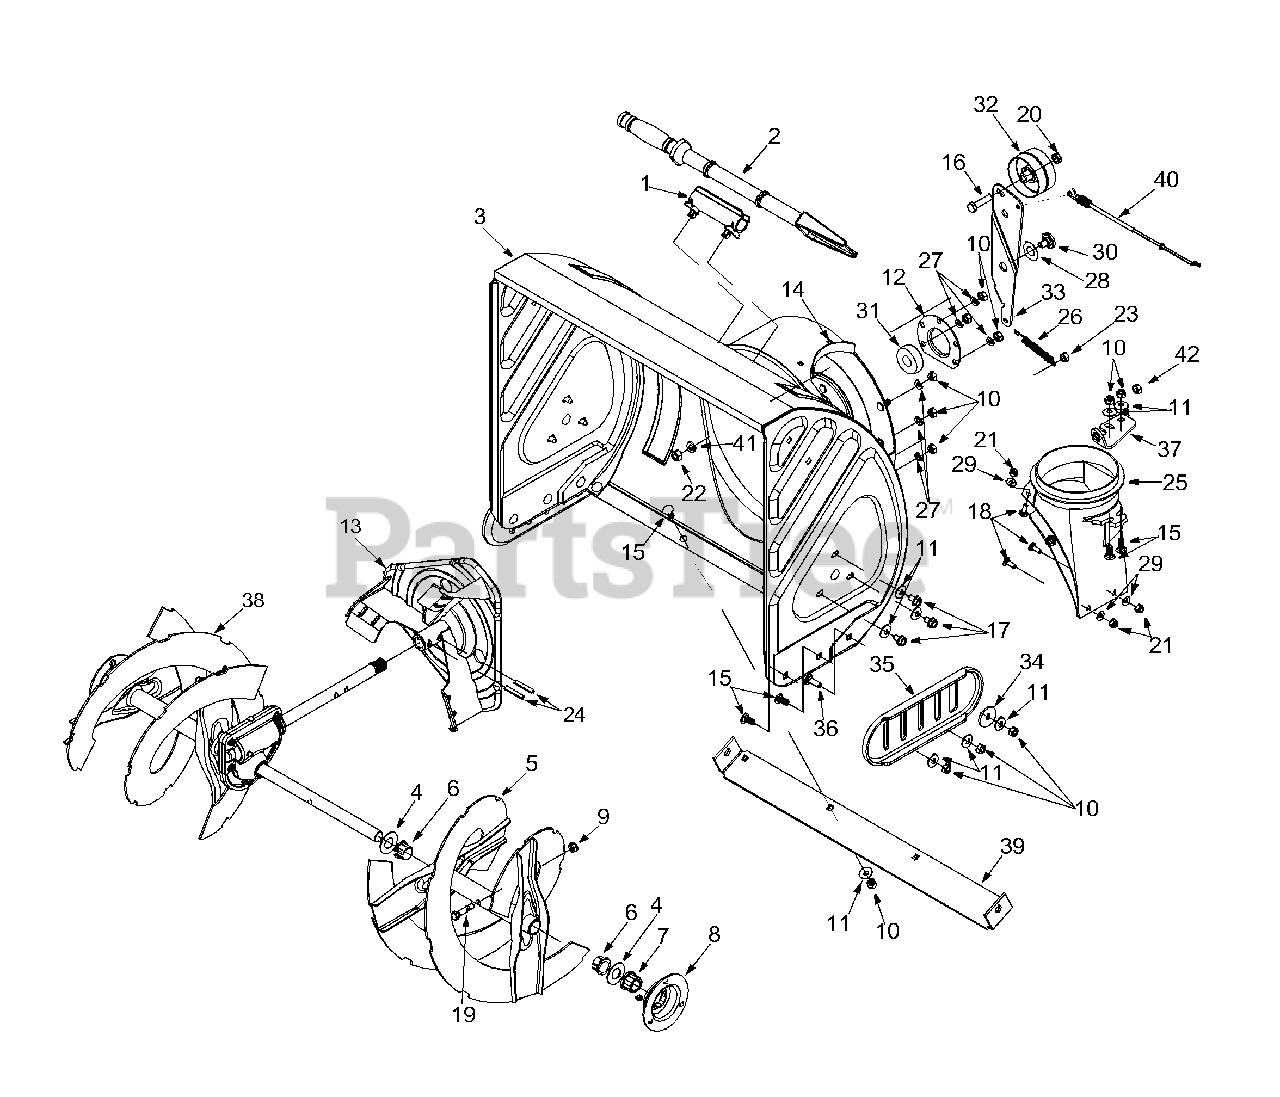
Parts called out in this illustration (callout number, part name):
1	Mount, Chute Clean-out Tool
2	Chute Clean-out Tool
6	Flange Bushing
7	Hex Flange Bearing
8	Bearing Housing
9	Lock Nut 5/16-18 Thd.
10	Hex Nut 5/16-18 Thd.
11	Bell Washer
15	Carriage Bolt 5/16-18 x .75
16	Hex Cap Screw 3/8-24 x 1.50
17	Hex Wash. TT Screw 5/16-18
18	Carriage Screw 1/4-20 x .75
19	Shear Bolt 5/16-18 x 1.5
20	Lock Jam 3/8-24
21	Hex Lock Nut 1/4-20
22	Hex Nut 3/8-16
23	Hex Nut 5/16-18
25	Chute Adapter
26	Extension Spring
27	Lock Washer 5/16
28	Fl-Wash. .565 x 1.25 x .02
29	FL-Wash .25 x .63 x .05
30	Shld. Screw
31	Ball Bearing
32	Flat Idler
34	Fl.-Wash. .38 I.D. x 1.38 O.D.
36	Carriage Screw 5/16-18
40	Auger Clutch Cable
41	L-Wash. 3/8
42	Plastic Bushing
